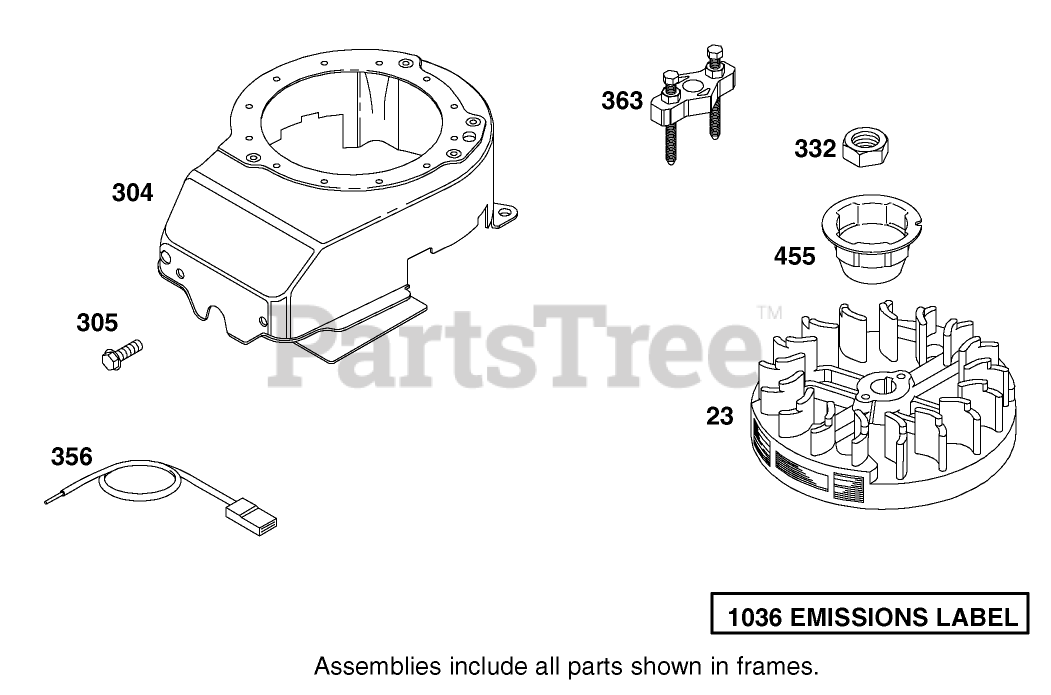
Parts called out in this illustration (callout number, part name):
23	Flywheel
304	Housing-Blower
305	Screw
332	Screw
356	Wire-Stop
363	Puller-Flywheel
455	Cup-Flywheel
1036	Label-Emissions
